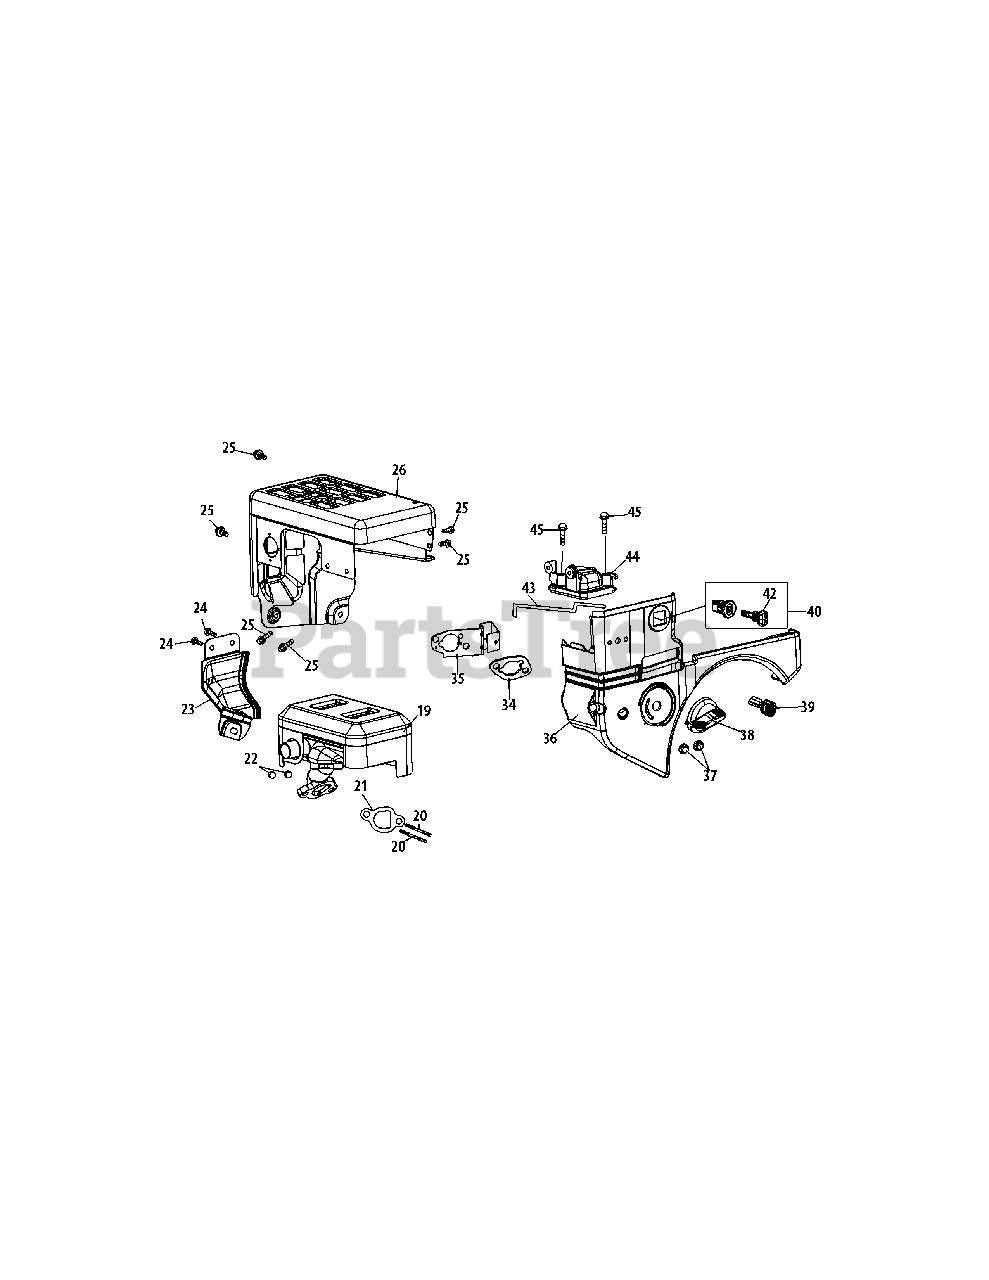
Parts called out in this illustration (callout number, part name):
19	Muffler Assembly
20	Muffler Stud M8×36
20	Muffler Stud Assembly
21	Muffler Gasket
22	Nut, M8
23	Exhaust Pipe Shield
24	Bolt M6×10
25	Bolt M6×12
26	Muffler Shield
34	Carburetor Gasket Plate
35	Choke Control
36	Air Cleaner Housing
38	Choke Knob
39	Throttle Control Knob
40	Key Switch
42	Key
43	Choke Push Rod
44	Heater Box
45	Bolt M6×25
